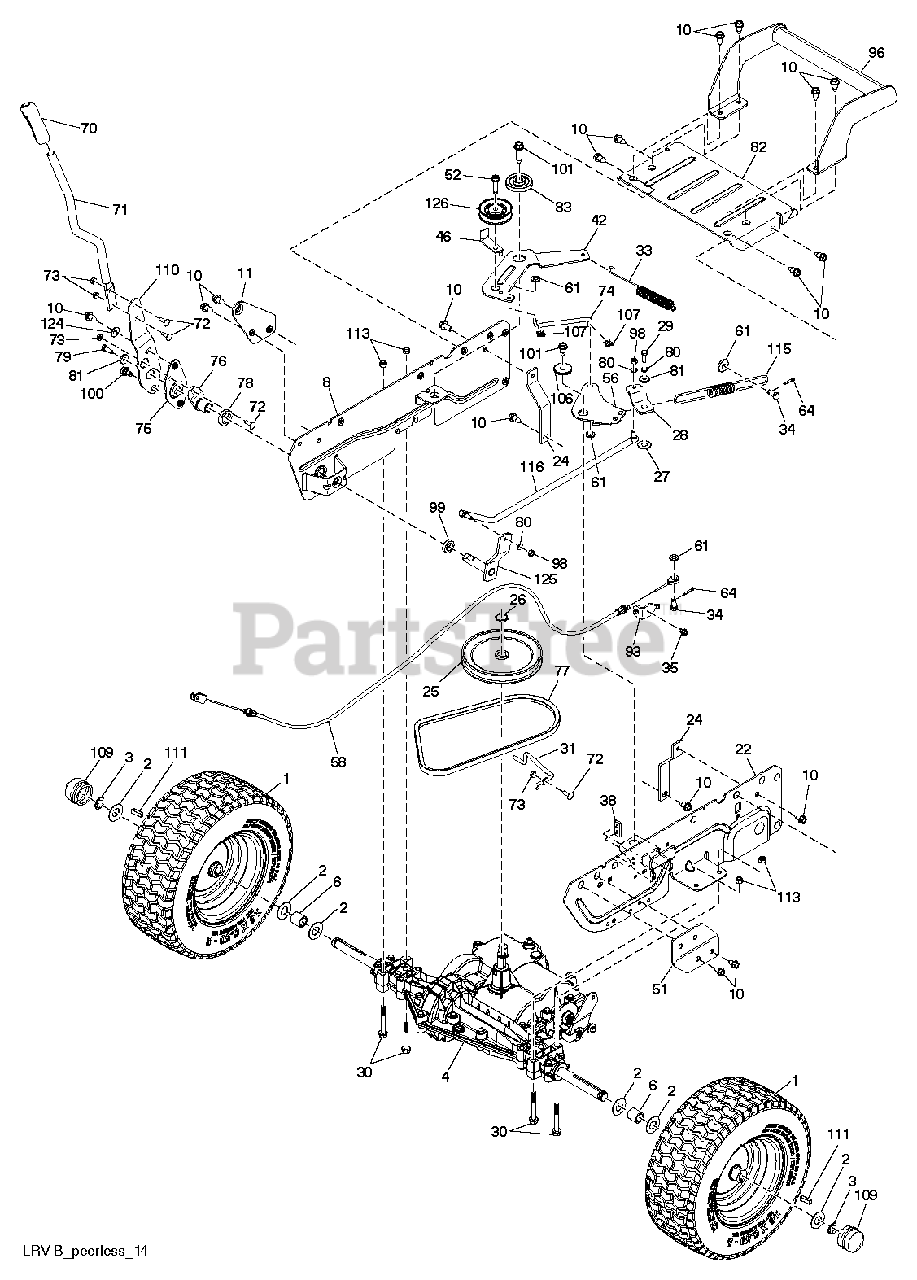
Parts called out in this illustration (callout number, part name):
1	WHEEL.TUBE.16X5.50-8.YELLOW.SN
3	E-RING LT
4	TRANSMISSION 4SPD MST 204-583A
6	SPACER, AXLE PVST
8	WELDMENT.SIDEPLATE.RH.X431
10	SCREW
11	BRACKET.SUPPORT.RH
22	WELDMENT.SIDEPLATE.LH.X431
24	STRAP.TORQUE.PMST.LRVB.PNT.431
25	PULLEY.INPUT.LRVB.PMST
26	RETAINING RING LT
27	WASH-SHFT PLT LT
28	ARM.SHIFTER.GEARDRIVE.PNT.431
29	Bolt, 1/4-20 unf Grade 8 w/Patch
30	BOLT
31	Drive Belt Keeper, Lrvb.X431
33	Tensioner Spring
34	PIN.HEX.CROSSDRILLED.3125
35	SCREW.1/4-20X3/8
38	PLATE NUT ZTR
42	ARM.CLUTHCHING.LRVB..PNT.431
46	KEEPER.BELT.CLUTCHING.ARM.X431
51	BRACKET SUPPORT.LH
52	Bolt, 5/16-18 X 1.25
56	BELLCRANK GROUNDDRIVE.LRVB.431
58	Brake Cable, LRVB Pmst
61	WASHER
64	COTTER PIN
70	GRIP.HANDLE.LIFT.PVC.BLACK
71	TUBE.SHIFT.LRVB
73	NUT.CROWNLOCK.1/4
74	LINK.CLUTCHING.ARM.BELLCRANK
75	MNTG BRKT. SHIFT ARM
76	HUB.SHIFT
77	Drive Belt, Ground.Lrvb.Pmst
78	SPACER.NYLON.
80	LOCKWASHER
81	WASHER LT
82	COVER.REAR.LRVB.PMSTX431
83	SPACER.RETAINER
93	BRAKE.MOUNT.CABLE.LRV
96	BUMPER.REAR.WELDMENT.BLACK.LRV
98	NUT LOCK CENTER 1/4 -28 FNTHD
99	SPACER.ARM.SHIFTER
100	BOLT.SHOULDER.5/16-18X
101	SCREW 3/8-16 X 1-1/2
106	SPACER.RETAINER
107	CLIP RETAINER
109	CAP.AXLE.FRONT.YELLOW
110	BRACKET, SHIFTER FLEX
111	SQUARE KEY
113	NUT LOCK HEX FLANGE 5/16-18
115	SPRING.BRAKE.ENGAGE.LRVB.PMST
116	LINK.STUD.BALL.GEARDRIV
124	WASHER.SRRTD.5/16
125	SUBASM.SHAFT.SIFT.GEARDRVE.431
126	PULLEY.V-IDLER.
